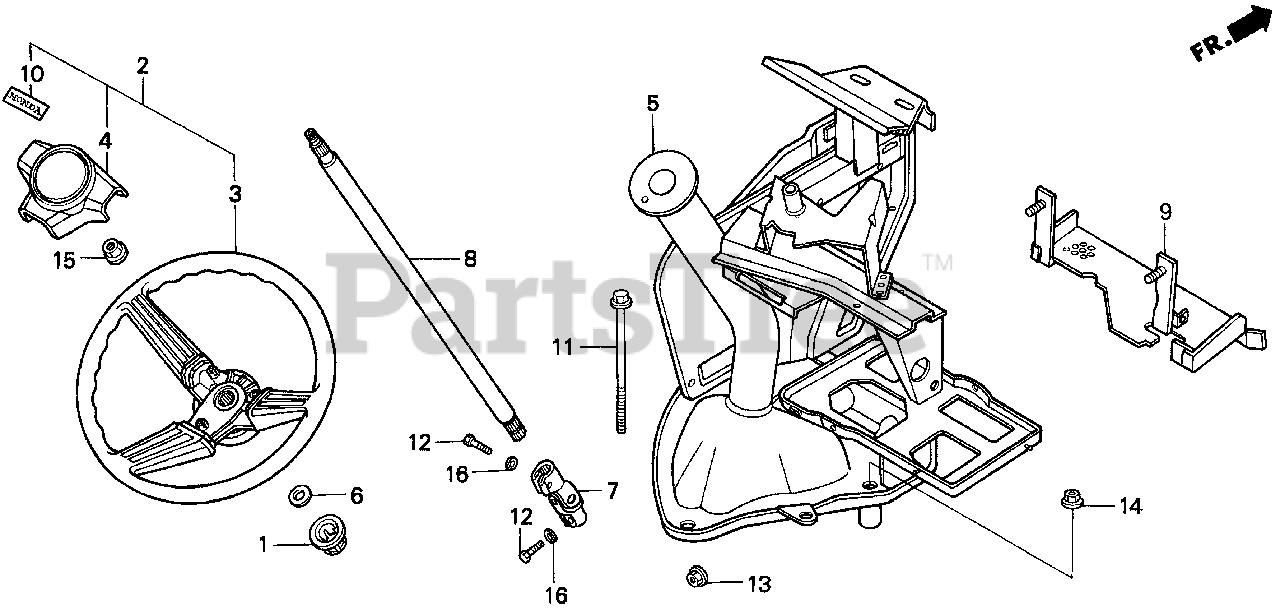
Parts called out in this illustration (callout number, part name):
1	BUSH, STEERING COLUMN
2	WHEEL ASSY., STEERING
3	WHEEL, STEERING
4	PAD, CENTER
5	COLUMN, STEERING
6	WASHER, STEERING COLUMN
7	JOINT ASSY., STEERING
8	SHAFT, STEERING
9	COVER, FR. PROPELLER SHAFT
10	MARK, EMBLEM (6H000-4149)
11	BOLT, ALTERNATOR
12	BOLT, HEX. (8X28)
13	NUT, FLANGE (6MM)
14	NUT, FLANGE (10MM)
15	NUT, SELF-LOCK (OHASHI)
16	WASHER, SPRING (8MM)
